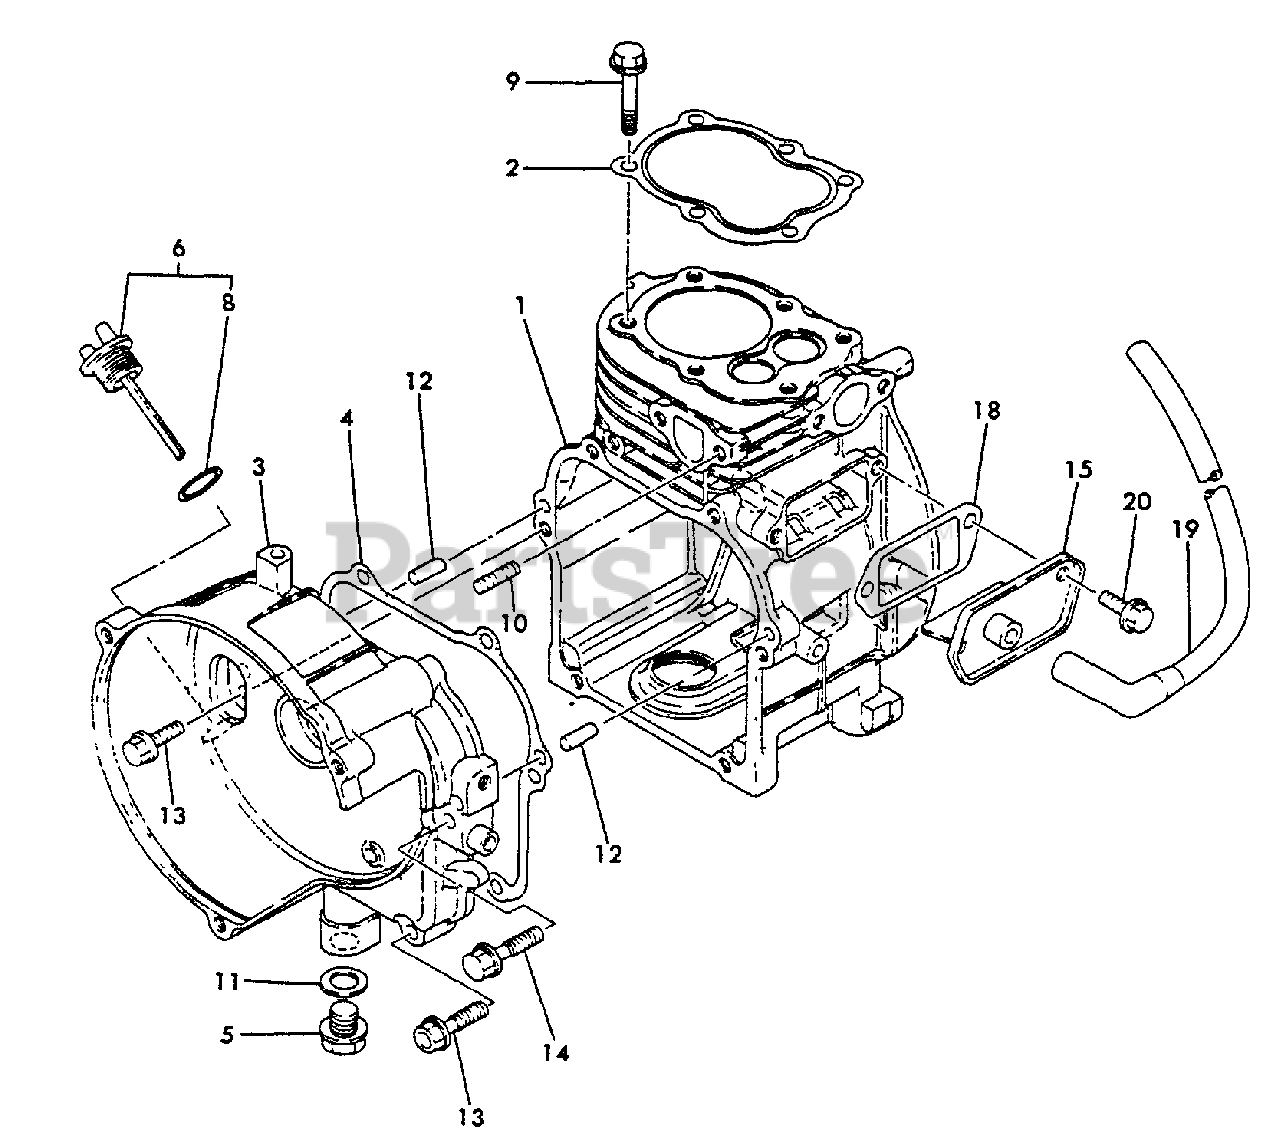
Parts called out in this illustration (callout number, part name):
1	CYLINDER BLOCK ASSY
2	GASKET, HEAD
3	COVER, CRANKCASE
4	GASKET, CRANKCASE
5	PLUG, DRAIN
6	CAP ASSY
8	O-RING - 18
9	BOLT - 6X35
10	BOLT - 6X16
11	GASKET
12	PIN - 6X16
13	BOLT - 6X25
14	BOLT - 6X30
15	VENT, FUEL TANK
18	GASKET, BREATHER
19	PIPE - BREATHER
20	BOLT - 6X8 -- PLATED
